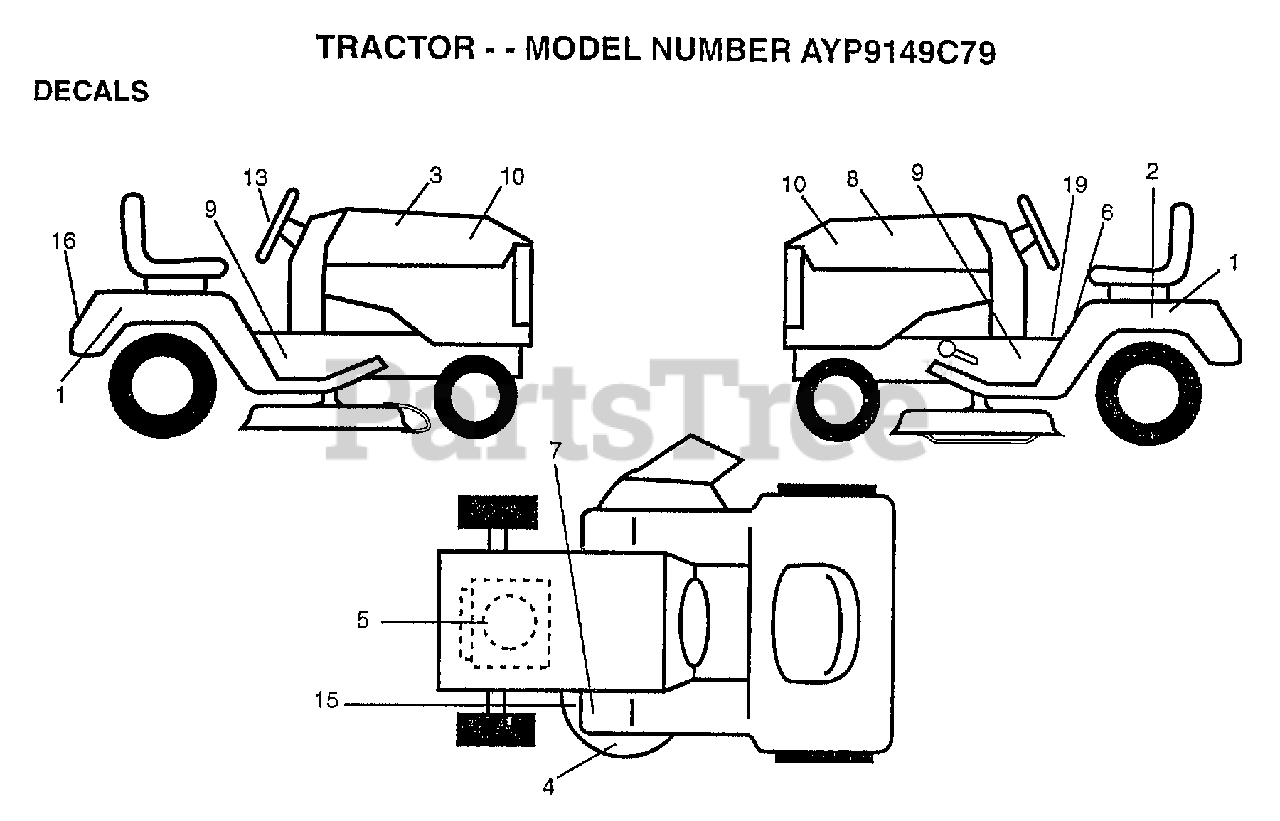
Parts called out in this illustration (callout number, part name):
1	DECAL.FENDER.WIZ
2	DECAL.BATRY.3-3908
3	DECAL.HD.RH.WIZAR
4	DECAL DECK WIZ +
5	DECAL, ENGINE
6	"DECAL DANGER,FEND"
8	DECAL.HD.LH.WIZAR
9	"DECAL.CHASSIS.42"""
10	DECAL.INS.HD.14.5
13	DECAL.INS.STRG.WL
15	DECAL
19	"DECAL INST,SADDLE"
